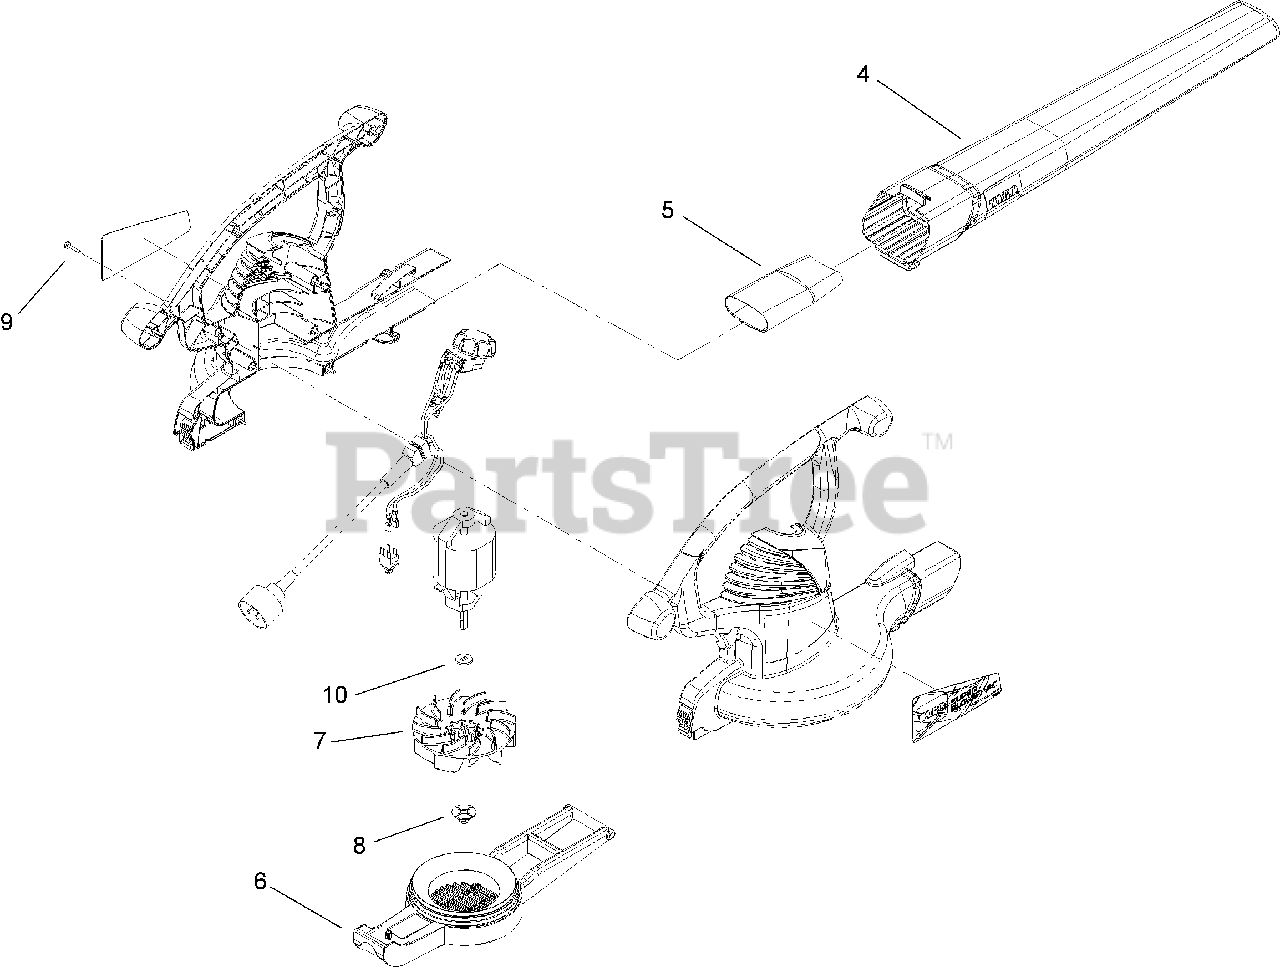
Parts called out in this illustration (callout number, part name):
4	TUBE-BLOWER
5	TUBE-EXTENSION, SUPER
6	COVER-INLET
7	IMPELLER-PLASTIC
8	NUT-IMPELLER
9	SCREW-PPH
10	WASHER-IMPELLER
